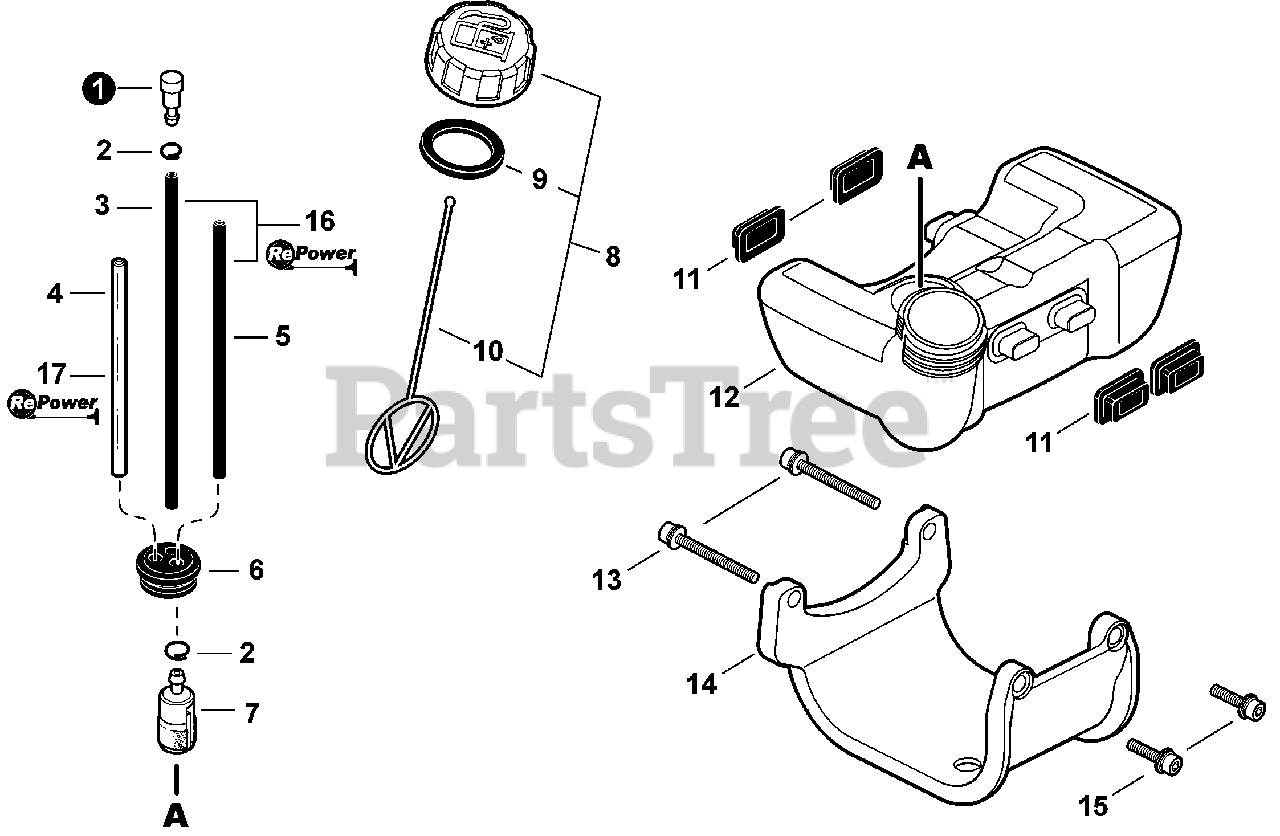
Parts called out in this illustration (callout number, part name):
1	VENT ASSY
2	CLIP Ø6.5MM
3	PIPE, FUEL 3×6×105 BLACK
4	PIPE, FUEL 3×6×85 CLEAR
5	PIPE 3×6×210 BLACK
6	GROMMET, FUEL
7	FILTER, FUEL 125-528
8	CAP ASSY, FUEL
9	GASKET, FUEL CAP
10	CONNECTOR, CAP L=123
11	CUSHION, FUEL TANK
12	TANK, FUEL
13	BOLT 5×40
14	GUARD, FUEL TANK
15	BOLT 5×18
16	PIPE - REPOWER BULK 3×6mm BLACK
17	PIPE - REPOWER BULK 3×6mm CLEAR
